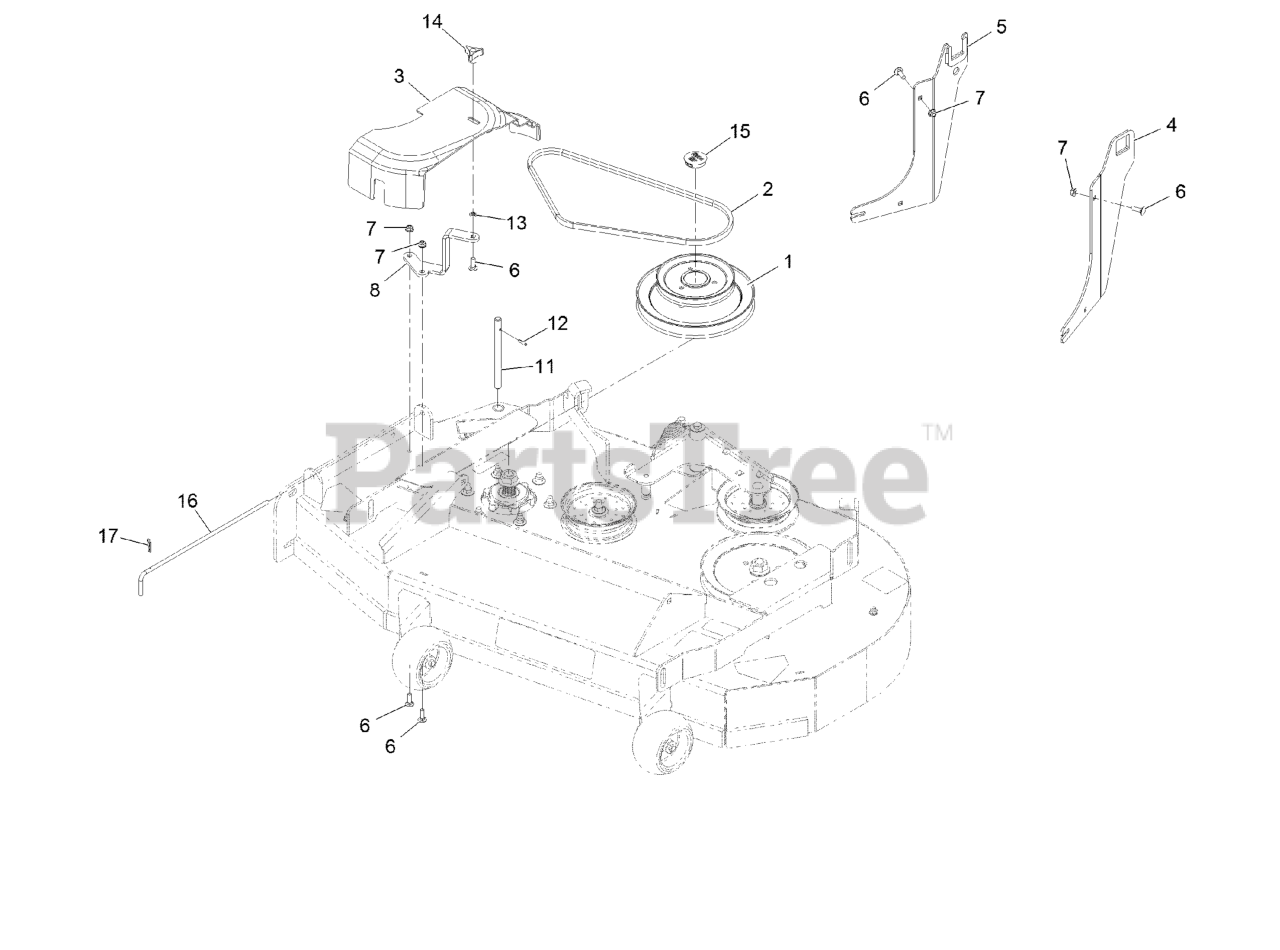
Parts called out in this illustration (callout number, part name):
1	JACKSHAFT-UV DRIVE, 44 SPLINED
3	COVER-BELT, UV 44
4	BRACKET ASM, LH
5	BRACKET ASM, RH
6	BOLT-CARR
7	NUT-HF, NI
8	BRACKET-BELT COVER 44
11	SHAFT-CATCHER, GRASS
12	PIN-ROLL
13	RING-RETAINING, BOLT
14	KNOB-3 PRONG
15	PLUG, BLACK NYLON 1.75
16	PIN,CHUTE PIVOT
17	PIN-COTTER
